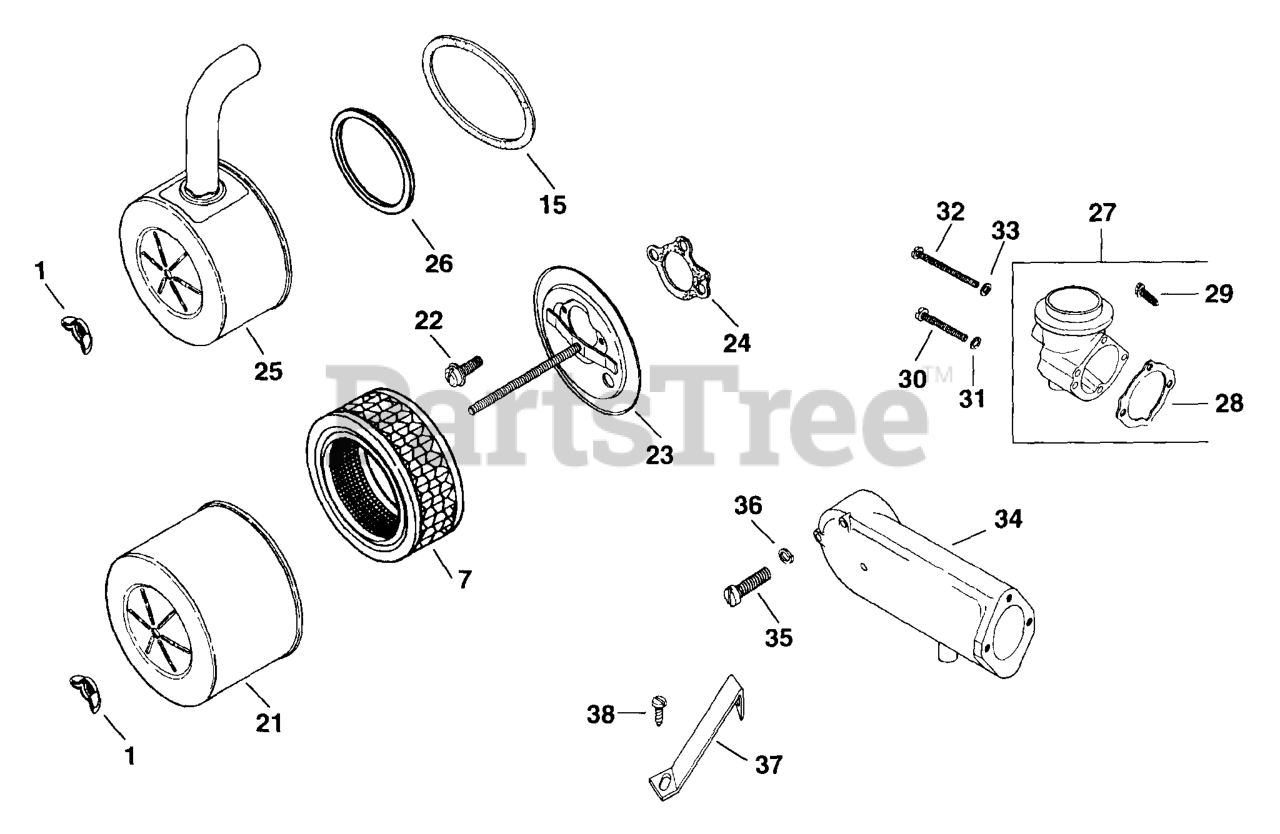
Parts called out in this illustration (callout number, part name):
1	NUT, WING 1/4-20 USE 25 100 15-S
7	ELEMENT, AIR CLEANER - Also available Retail Packaged 45 883 02-S1 Air Filter Kit
25	COVER - (#DSC)
